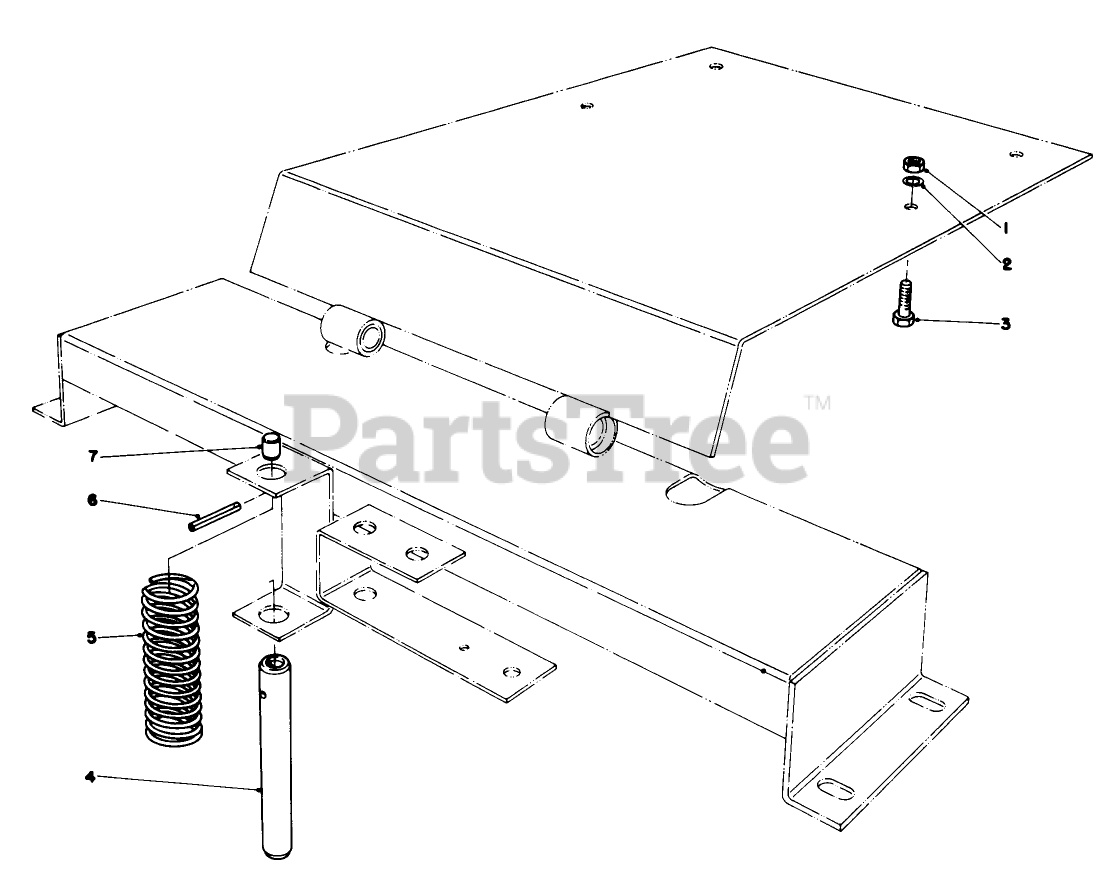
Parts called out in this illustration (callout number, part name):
1	NUT-HEX
2	WASHER-LOCK/SP
3	SCREW-HH
4	PIN-SWITCH, SEAT
5	COMP SPRING
6	PIN-ROLL, SLOTTED
7	PIN-PEDAL
